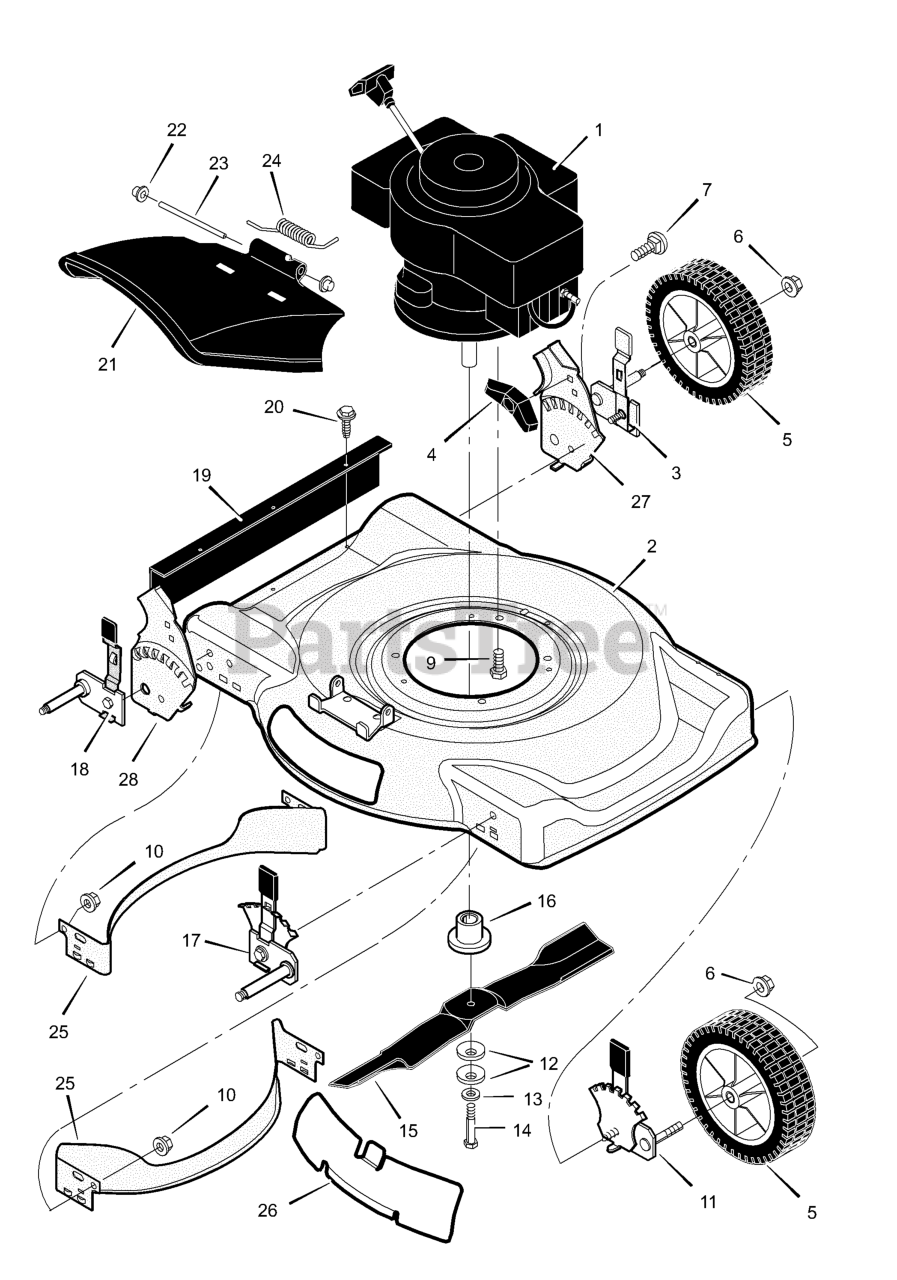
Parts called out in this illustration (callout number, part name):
1	Engine
2	Housing
3	Height Adjuster, Left Rear
5	Wheel and Tire
6	Locknut, Flange
7	Bolt, Carriage
9	Bolt, Engine
10	Nut
11	Height Adjuster, Left Front
12	Washer, Belleville
14	Bolt, Hex
16	Adapter, Blade
17	Height Adjuster, Right Front
18	Height Adjuster, Right Rear
19	Guard, Rear
21	Deflector, Chute
22	Push-On Cap
23	Pin, Pivot
26	Plate, Mulcher
27	Bracket, Left Handle
28	Bracket, Right Handle
